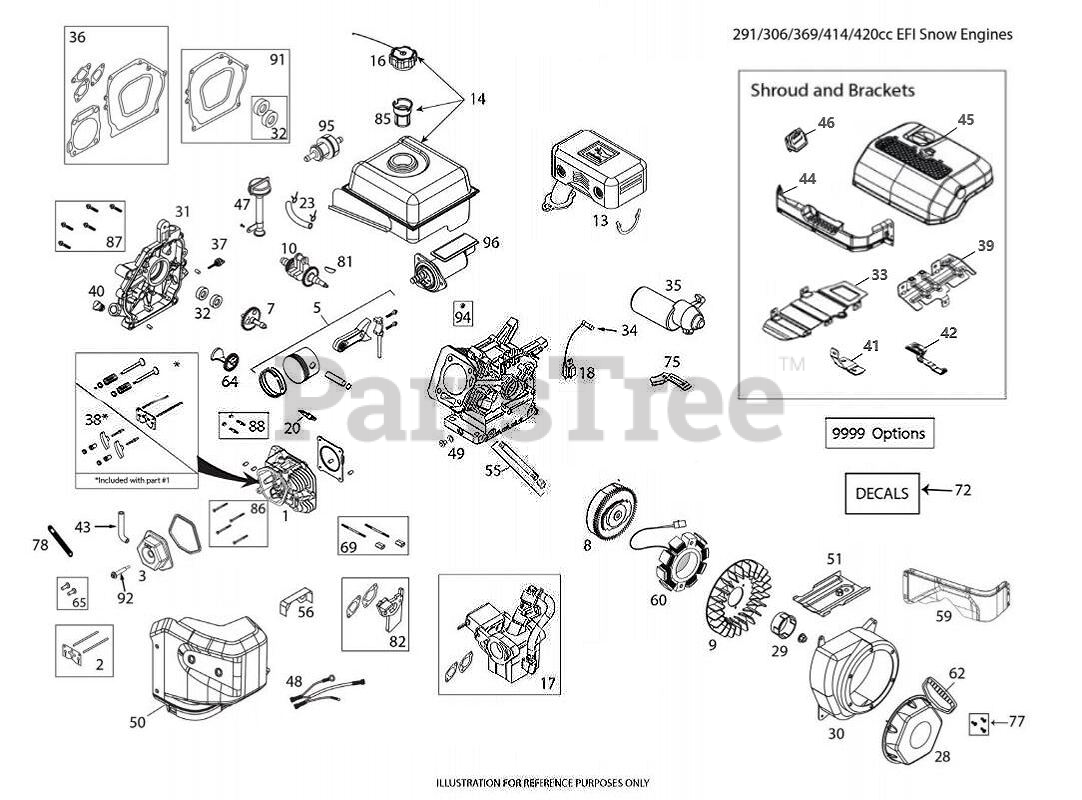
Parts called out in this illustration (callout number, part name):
1	CYLINDER HEAD LCT 178 INCLUDES
2	PUSH ROD TAPPET KIT
3	VALVE.COVER.LCT.414CC.
5	PISTON ROD ASM.LCT SK3691400.1
7	CAMSHAFT(SK4141600)
8	FLYWHEEL.EL.ST.SKSN4408.1
9	FLYWHEEL.FAN(SK4144000)
10	CRANKSHAFT KEYED #18 LCT 414C
18	IGNITION.COIL.(CDI).291-414CC
20	SPARK.PLUG(2083810)
20	PLUG.SPARK
23	Fuel Hoses
29	STARTER CUP
32	OIL SEAL KIT NON-GENERATOR
34	SPARK.PLUG.BOOT.SNW,SKSN4691.1
36	GASKET KIT ENGINE LCT 369
37	DIPSTK.OIL.BLK.LCTSK4143711.1
38	ROCKER ARM KIT
40	NONREMVABLE.OIL.PLUG(SK4143715
42	Brackets
43	TUBE.BREATHER.LCT.219CC/414CC
49	OIL.DRAIN.PLUG
51	SHIELD.CYLINDER.SNOW(SK4141010
55	OIL PIPE DRAIN EXTENDED.LCT SK
60	Charging Station
62	STARTER.GRIP.SNOW.LCT.SKSN0603
64	COUNTER WEIGHT KIT
65	TAPPET KIT.LCT.SK2911005.1
69	STUD.CARB.MOUTING.KIT.414CC
75	SHIELD.U/FYWHL.CHARG(SKSN4604)
77	BOLT.KIT.RECOIL.LCT.ALL.ENGINE
78	STRAP.RETAINING.TUBE.BREATHER.
81	KEYS.FLYWHEEL.136/291CC.5PACK
82	SPACER.CARBURETOR.414CC.LCT
85	STRAINER.FUEL.TANK.LCT.208CC
86	KIT.BOLT.CYLINDER.HEAD.(4PC)
87	KIT.BOLT.CRANKCASE.COVER.414CC
91	GASKET KIT CRANKSHAFT.LCT
92	CENTER VALVE COVER BOLT
